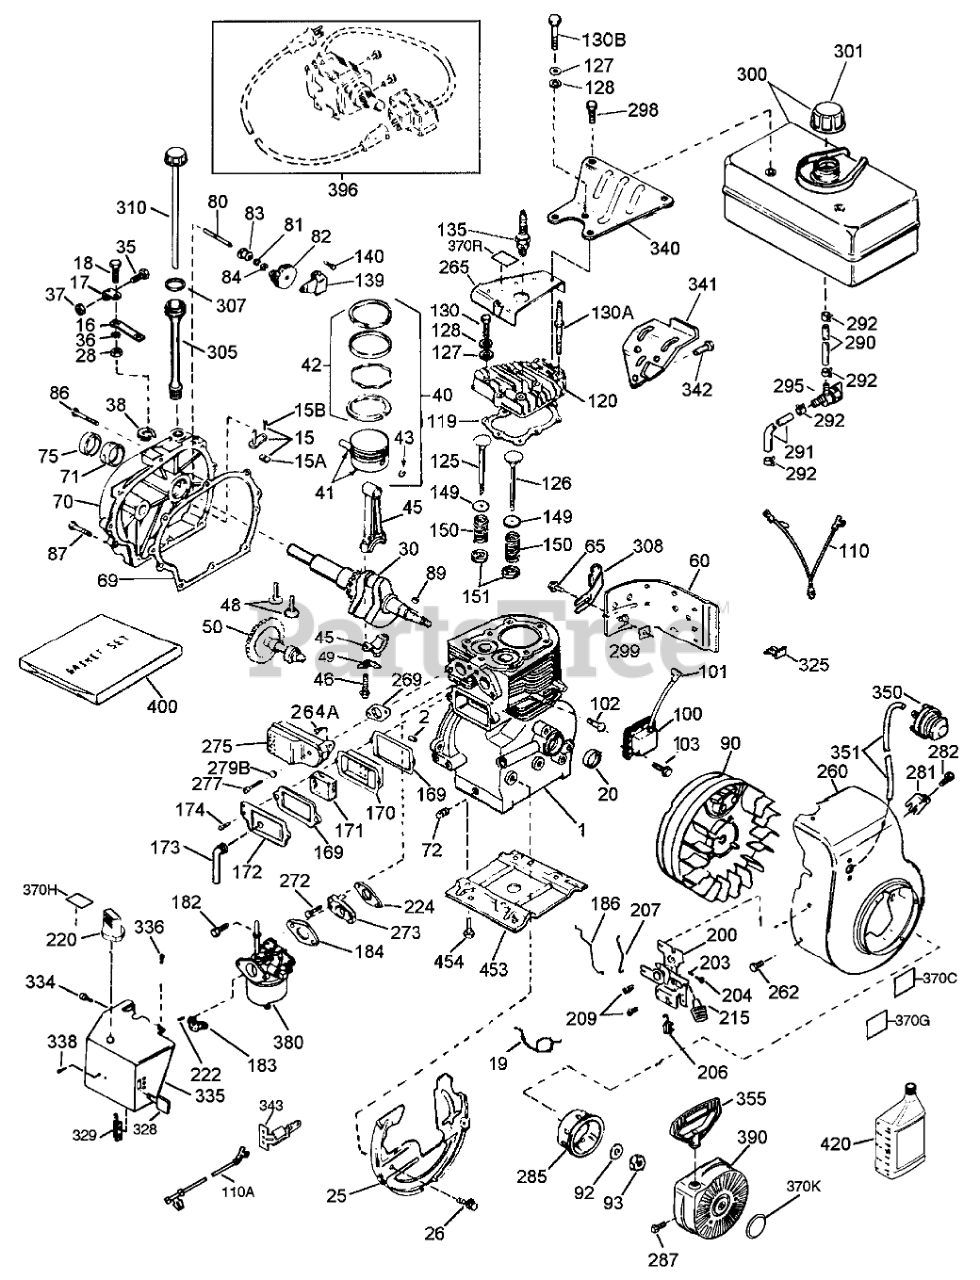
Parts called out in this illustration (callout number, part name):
1	Cylinder (Incl. Ref. #2,20 & 72)
2	Pin-Dowel
15	Governor Rod (Incl. Ref. #15A & 15B)
15A	Yoke-Governor
15B	Screw (6-40x5/16)
16	Lever-Governor
17	Clamp-Lever, Governor
18	Screw (T-15, 8-32x7/16)
19	Spring-Throttle
20	Oil Seal
25	Baffle-Housing, Blower
26	Screw (1/4-20x19/32)
28	Nut-Lock
30	Crankshaft
35	Screw
36	Washer-Lock
37	Nut-Lock
38	Ring-Retaining
40	Piston, Pin & Ring Set (Std.)
40	Piston, Pin & Ring Set (.010" OS)
41	Piston & Pin Assembly (Std.) (Incl. #20)
41	Piston & Pin Ass-y (.020" OS)(Incl. Ref. #43)
41	Piston & Pin Ass-y (Std.)(Incl. Ref. #43)
42	Ring Set (Std.)
42	Mudguard R.H.
42	Mudguard L.H.
43	Ring-Retaining, Piston Pin
45	Connecting Rod Ass-y (Incl. Ref. #46 & 49)
46	Bolt-Connecting Rod
48	Lifter-Valve
49	Dipper-Oil
50	55012A GIL SNWTHWR
60	Extension-Blower Hsng.
65	Screw
69	Gasket-Cover, Cylinder
70	Cylinder Cover (Incl. Ref. #71, 75, & 80)
71	Bushing-Crankshaft
72	Plug-Drain, Oil (SQH 1/4-18)
75	Oil Seal
80	Shaft-Governor
81	Washer-Flat
82	Governor Gear ASM
83	Spool-Governor
84	Ring-Retaining
86	Screw (1/4-20 x 1-1/4)
87	Screw
89	Key-Flywheel
90	Flywheel
92	Washer-Belleville
93	Nut
100	Solid State Ignition (Incl. 101)
101	Cover-Spark Plug
102	Stud-Mounting, Solid State
103	Screw (T-15, 10-24 x 15/16)
110	Ground Wire
110A	Wire-Ground
119	Cylinder Head Gasket
120	Cylinder Head (Incl. 3 of 131)
125	Exhaust Valve (Std.)(Incl. Ref. #151)
125	Exhaust Valve (1/32" OS)(Incl. Ref. #151)
126	Intake Valve (1/32" OS)(Incl. Ref. #151)
126	Intake Valve (Std.)(Incl. Ref. #151)
127	Washer-Flat
128	Washer-Belleville
130	Screw (5/16-18 X 2-1/2)
130A	Screw (5/16-18 X 2-1/2)
130B	Screw (5/16-18 X 2-1/2)
135	Spark Plug-Resistor (R J19 L M)
139	Bracket, Governor
140	Screw, Torx T-25
149	Cap-Spring, Valve
150	Spring-Valve
151	Keeper-Spring, Valve
169	Gasket-Cover, Valve
170	Body-Breather
171	Element-Breather
172	Cover-Valve
173	Tube-Breather
174	Screw
182	Screw (T-30, 1/4-20 X 27-32)
183	Bracket-Choke
184	Gasket-Carburetor
186	Governor Link
200	Control Bracket (Incl. Ref. #203, 204, & 206)
203	Spring-Compression
204	Screw (T-10, 5-40x7/16)
206	Terminal
207	Link-Throttle
209	Screw (10-32 x 1/2)
215	Knob-Control
220	Knob-Choke
222	Screw (10-32 x 1/2)
224	Gasket-Pipe, Intake
260	Blower Housing
262	Screw
264A	Screw
265	Cover-Head, Cylinder
269	Gasket-Exhaust
272	Screw
273	481-1279 SENATOR RO
275	Muffler
277	Screw (5/16-18 X 2)
279B	Washer
281	Screw
282	Screw (8-32 x 3/8)
285	Starter Cup
287	Screw (8-32 x 21/64)
290	Line-Fuel (8.62)
291	Line-Fuel
292	Clamp-Line, Fuel
295	Valve-Shut Off, Fuel
298	Screw (1/4-15x7/8)
299	Nut-U Type
300	Fuel Tank (Incl. Ref. #292 & 301)
301	Cap-Fuel
305	Tube-Fill, Oil
307	O-Ring
308	Clip-Tube, Fill
310	Gauge Oil ASM
325	Clip-Wire
329	Terminal
334	Screw (8-32 X 5/16)
335	Carburetor Cover
336	Screw (10-32x1/2)
338	Screw (8-32 x 3/8)
340	Bracket-Fuel Tank
341	Bracket-Fuel Tank
342	Screw (1/4-20x19/32)
343	Bracket-Switch, Key
350	Primer ASM
351	Line-Primer
355	Handle-Starter, Mitten Grip
370C	Decal-Primer, International Symbol
370G	Instruction Decal
370H	Choke Decal
370K	Decal-Tecumseh Logo for Top of Recoil Starter
370R	Decal-Warning (Bilingual)
380	Carburetor (Incl. Ref. #184)
390	Starter-Rewind
396	Electric Starter Motor (110 Volt)
400	Gasket Set
420	4 Cycle Oil, SAE 30 (Quart)
453	Base Engine
454	Screw
